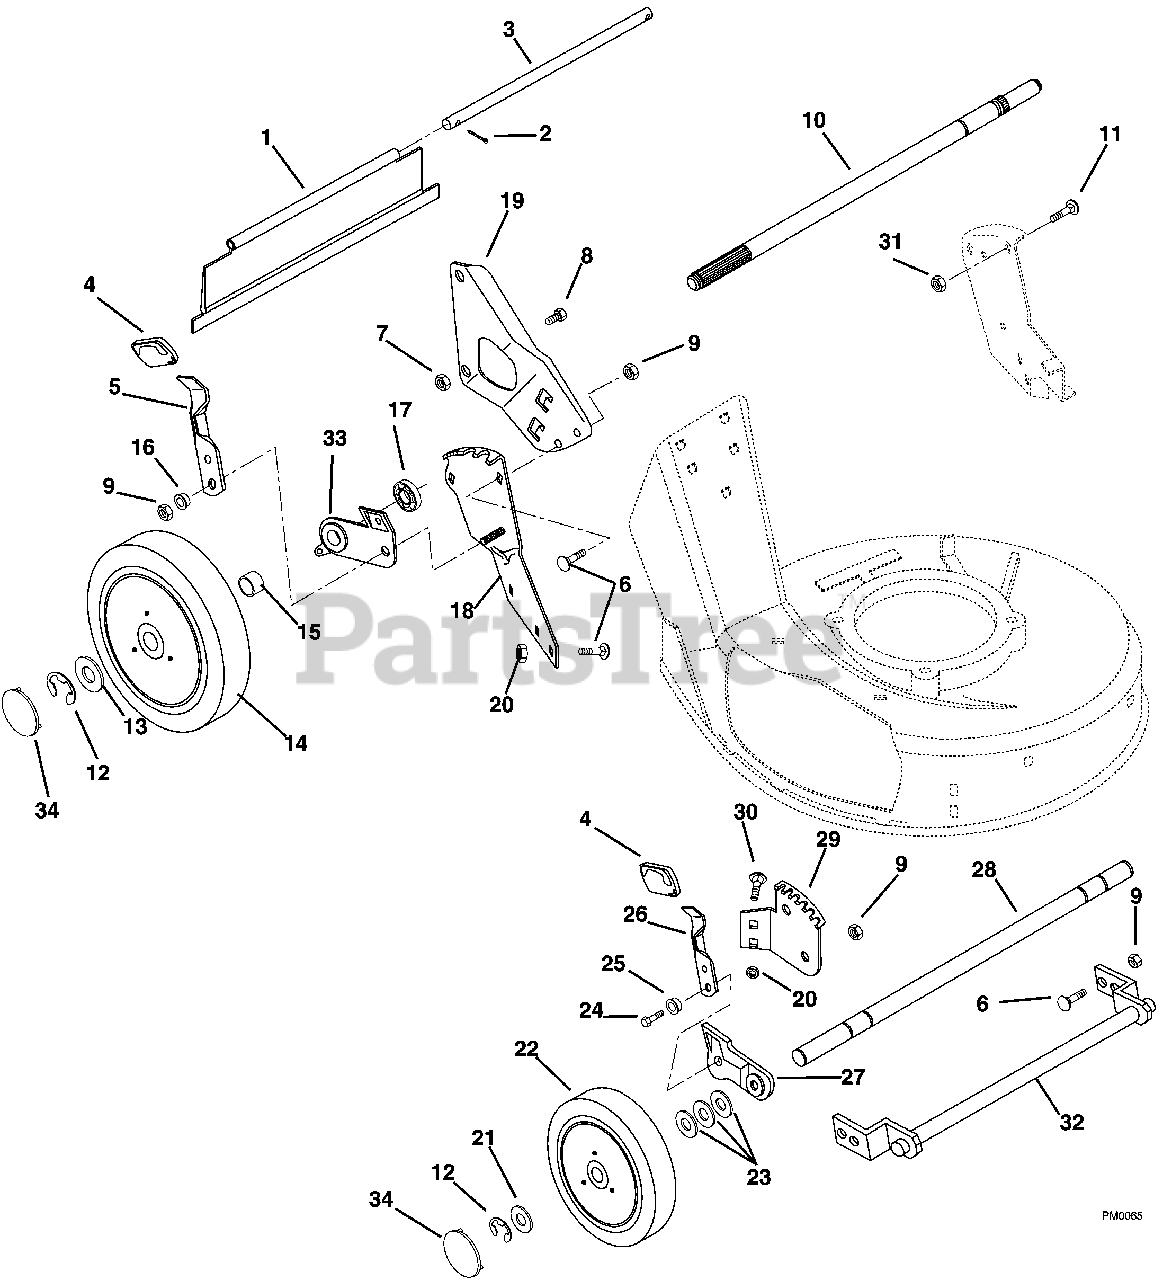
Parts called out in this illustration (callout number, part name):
1	Rear Protective Guard, Self Propelled
2	Pin-Cotter .06 x .50
5	Height Adjustment Lever
6	Bolt-Round Head Square Short Neck .31-18 x .62
7	Nut-Locking-Center .38-16
8	Handlebar Stud
9	Nut-Locking-Center .31-18
11	Bolt-Round Head Square Short Neck .31-18 x 1.00
12	Ring-Retaining-External .500 x .042
13	Washer-Flat-Steel .505 x .880 x .072
14	Left Hand WheelRear
15	Spacer Tube
16	Bushing-Flange .312 x .500 x .344 x .880
17	Bearing-Ball .625 x 1.383 x .50 (600 C)
18	Rear Quadrant-Left Hand
18	Bracket-Handlebar Mounting-Right Hand
20	Nut-Locking-Flanged .31-18
21	Washer-Flat-Steel .505 x .880 x .072
22	Wheel-Front
23	Washer-Flat-Steel .520 x .827 x .062 (580 RS, 580 RSE, 580 RSW)
24	Bolt-Hex .31-18 x 1.00 Grade 5 (580 RS, 580 RSE, 580 RSW)
25	Bushing-Flange .312 x .500 x .344 x .880
26	Lever, Front Height Adjustment (580 RS, 580 RSE, 580 RSW)
27	Left Hand Bracket Assembly (580 RS, 580 RSE, 580 RSW)
28	Front Axle (580 RS, 580 RSE, 580 RSW)
29	Front Quadrant, Left Hand (580 RS, 580 RSE, 580 RSW)
30	Bolt-Round Head Square Neck .31-18 x .50 Grade 5 (580 RS, 580 RSE, 580 RSW)
31	Nut-Locking-Nylon .31-18
32	De-Thatcher Retainer Weldment (600 C)
33	Rear Adjuster Bracket-Right Hand (600 C)
34532	Hubcap (Qty. 4 on 580 RS, 580 RSE, 600 C - Qty. 2 on 580 RSW)
